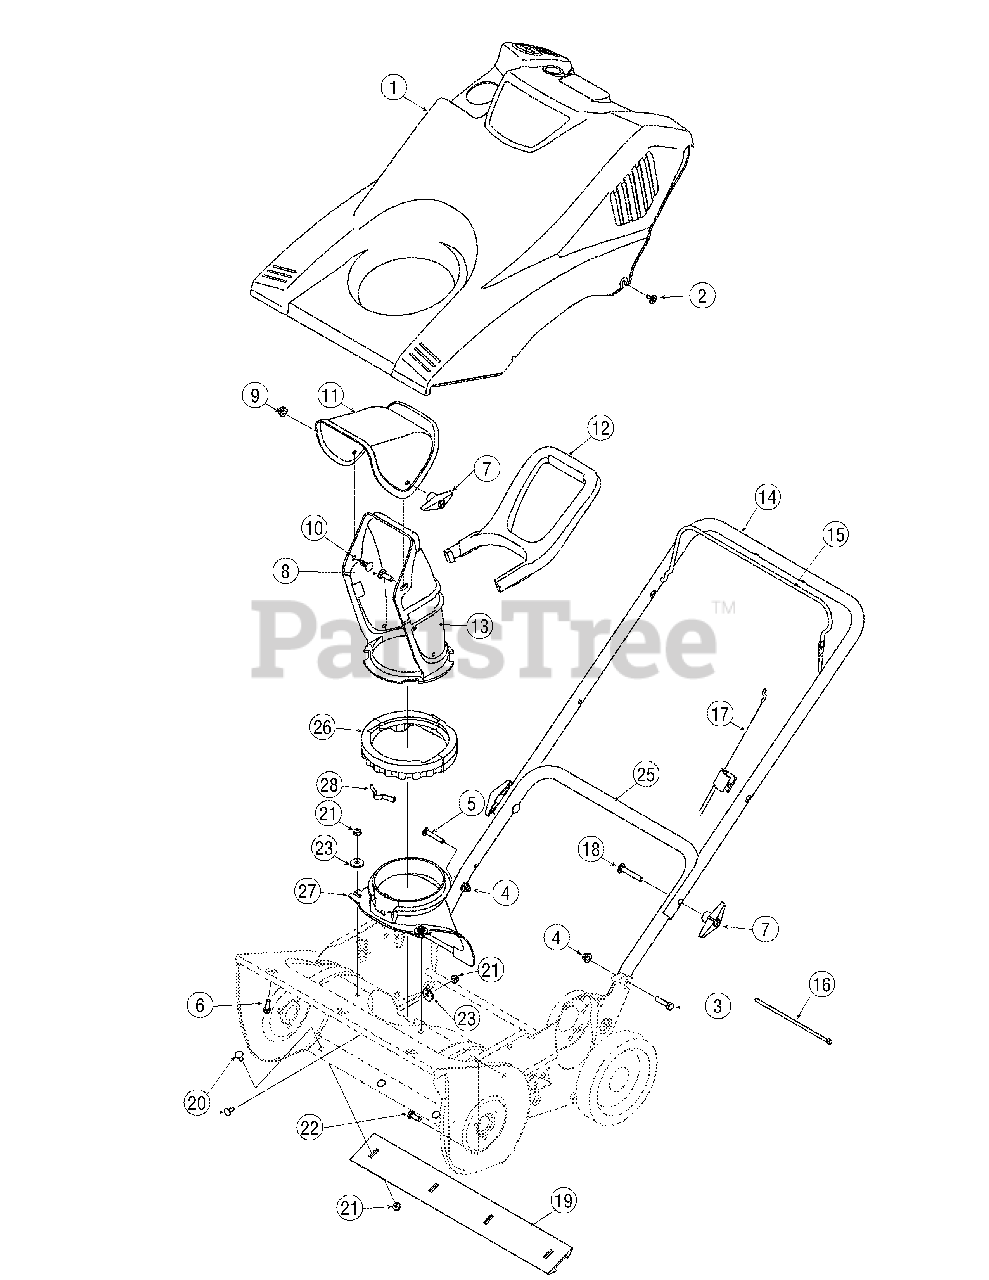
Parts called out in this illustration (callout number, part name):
1	Shroud
2	Hex Screw, 10-16 x .625
3	Hex Flange Screw, 5/16-18 x 1.25
4	Flange Lock Nut, 5/16-18
5	Hex Flange Screw, 5/16-18 x 1.50
6	Hex Screw, 1/4-15 x .750
7	Wing Nut, 5/16-18
8	Carriage Bolt, 5/16-18 x 1.00
9	Flange Lock Nut, 5/16-18
10	Carriage Bolt, 5/16-18 x .750
11	Upper Chute
12	Chute Handle
13	Lower Chute
14	Upper Handle
15	Bail Control
16	Cable Tie, 3/16 x .05 x 7.4
17	Clutch Cable
18	Carriage Bolt, 5/16-18 x 2.00
19	Shave Plate, 21"
20	Carriage Screw, 1/4-20 x .62
21	Flange Lock Nut, 1/4-20
22	Hex Screw, 5/16-18 x .75
23	Flat Washer, .265 x .938 x .120
25	Lower Handle
26	Lower Chute Ring
27	Chute Adapter
28	Chute Adjustment Spring
